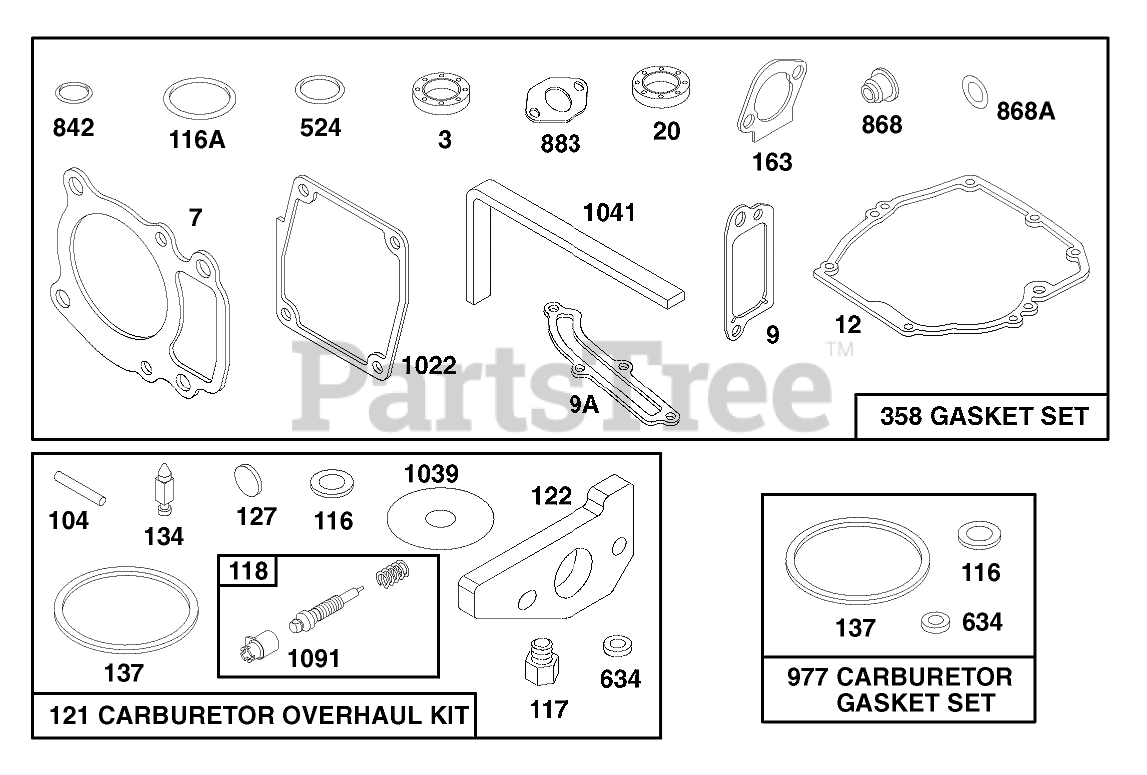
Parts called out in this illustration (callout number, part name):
3	SEAL - OIL
7	CYLINDER HEAD GASKET
9	BREATHER GASKET
9A	GASKET-BREATHER
12	ENGINE BASE GASKET
20	SEAL-OIL
104	FLOAT HINGE PIN
116	SEALING GASKET
116A	O RING SEAL
117	Jet-Main
118	VALVE/SPRING - NEEDLE
121	KIT-CARBURETOR OVERHAUL
122	ADAPTER ASSEMBLY
127	PLUG - WELCH
134	Valve-Inlet(Includes Seat)
137	FLOAT BOWL GASKET
163	AIR CLEANER GASKET
358	GASKET SET
524	O-RING
634	SEAL WASHER
842	O-RING
868	SealAssy-Valve
868A	Seal-Valve
883	EXHAUST GASKET
977	CARBURATOR GASKET SET
1022	ROCKER COVER GASKET
1039	FLOAT LIMITER
1041	SEAL - FOAM
1091	CAP - LIMITER
